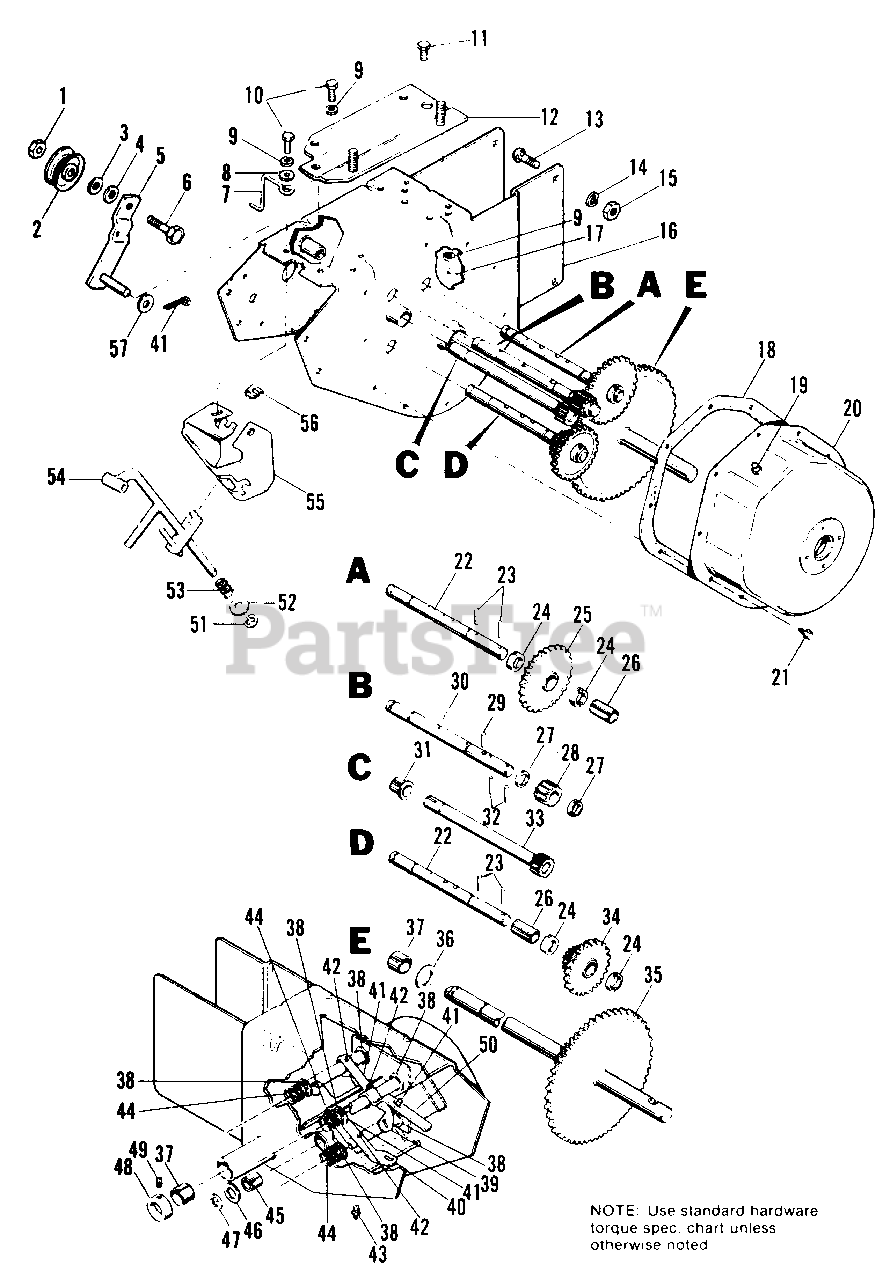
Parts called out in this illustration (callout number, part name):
1	LOCKNUT, Hex, Flange, 3/8-16
2	PULLEY, Idler
2	PULLEY, Idler (1690209 & 1690255 Only)
3	SPACER (1690379, 1690380 & 1690442 Only)
4	WASHER, Plain, 5/16
5	ARM ASSY., Idler
6	SCREW, Special
7	STOP, Belt
8	WASHER, Plain, 1/4
9	LOCKWASHER, 5/16 (Qty. 2 used on 1690379 & 1690442)
10	CAPSCREW, Hex Hd., 5/16-18 x 1
11	CAPSCREW, Hex Hd., 5/16-18 x 3/4 (1690380 Only)
12	SUPPORT ASSY., Engine (1690380 Only)
13	BOLT, Carriage, 3/8-16 x 3/4
14	LOCKWASHER, 3/8
15	NUT, Hex, Full, 3/8-16
16	ENGINE BASE & FRAME ASSY.
17	NUT, Hex, Full, 5/16-18
19	FITTING, Lube
20	CASE ASSY., Gear
21	SCREW, Taptite, 1/4-20 x 3/8
22	SHAFT, Intermediate
23	PIN, Roll, 1/8 x 1
24	COLLAR, Thrust
25	GEAR & BEARING ASSY.
27	COLLAR, Thrust
28	PINION, Reverse
29	PIN, Spring, 5/32 x 1
30	SHAFT, Reverse
31	BEARING, Bronze
32	PIN, Spring, 1/8 x 3/4
33	SHAFT ASSY., Gear
34	GEAR & BEARING ASSY.
35	AXLE & GEAR ASSY.
38	RING, Retaining
39	LINK, Shift, Lo
40	LINK, Shift, High
41	PIN, Cotter, 3/32 x 3/4
42	PIN, Cotter, 3/16 x 1-1/4
43	FITTING, Grease
47	RING, Retaining
48	COLLAR, Set
49	SETSCREW, 5/16-18 x 3/8
50	LINK, Shift, Reverse
51	RING, Retaining
52	WASHER, Plain, 7/16
54	SHIFT ROD ASSY., Lower
55	GUIDE, Pattern
56	NUT, Retainer, 5/16
